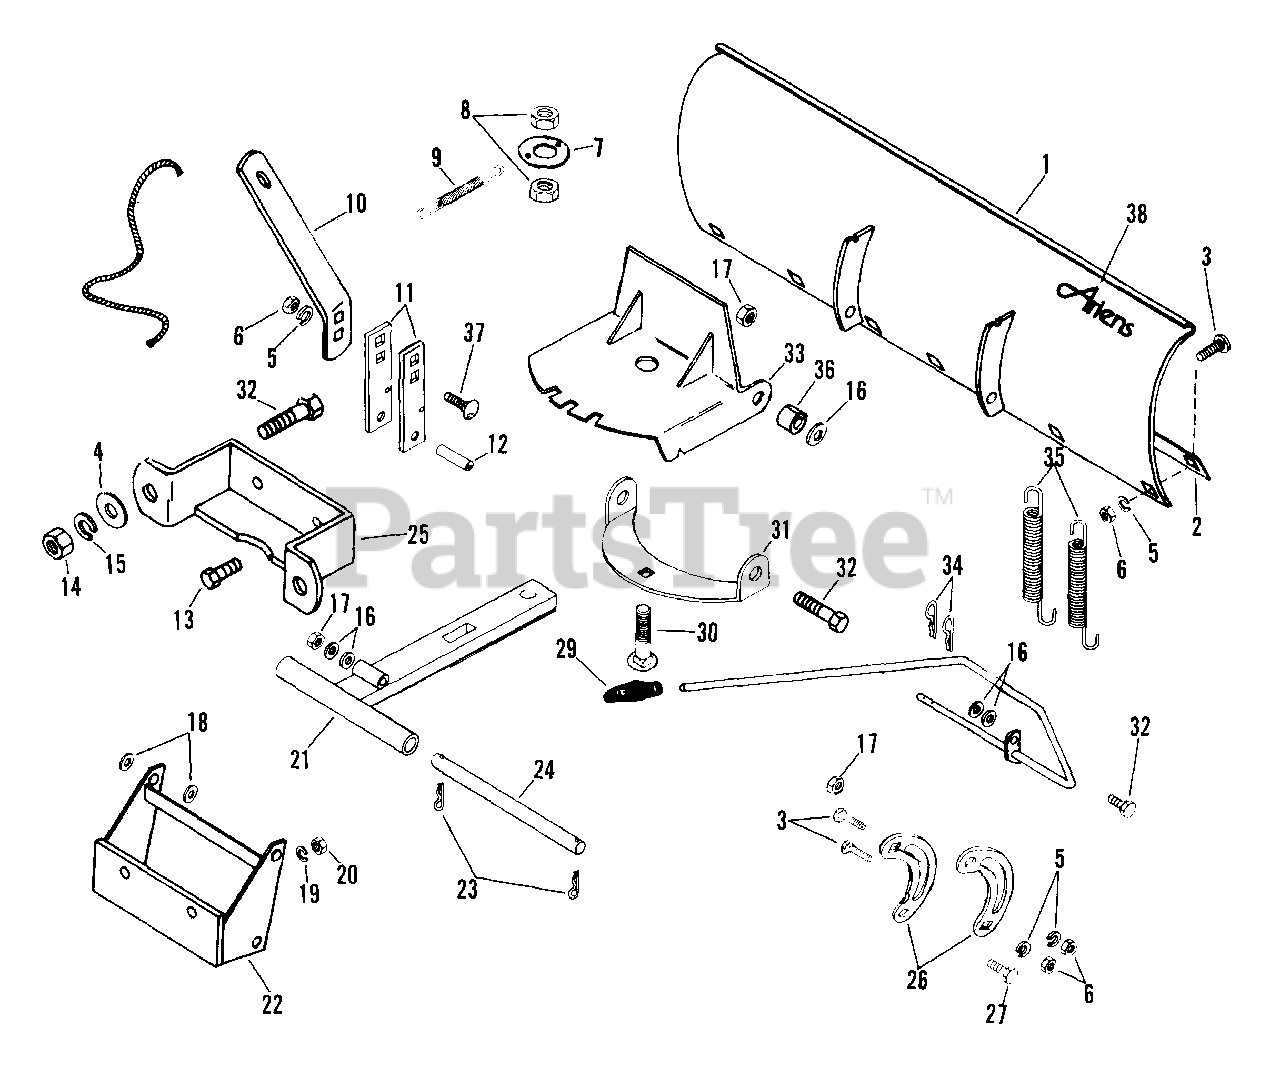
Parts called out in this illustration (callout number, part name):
1	40 INCH SNOW BLADE
2	WEAR BAR
3	BLT-RDHDSQSHNK .38-16X1.00 PL
5	WSHR-LK .375X.115 HVY PL
6	NUT-HEX .375-16
7	LATCH SPRING WASHER
8	NUT-JAM .75-10 PL
9	SG-TENS .106X.56X2.75 WLD 10
10	PIVOT BLOCK EXTENSION
11	BAR PIVOT LOCK
12	PIN-ROLL .250X1.00
13	BLT-HEX .25-20X1.00 PL GR5
14	NUT .50-13 PL
15	WSHR-LK .500X.151 HVY PL
16	WSHR-FL-STL .531X1.062X.095 PL
17	NUT-LK-CTR .50-13
18	WSHR-FL-STL.656X1.312X.095 PL
19	WSHR-LK .250X.077 HVY PL
20	NUT-HEX .250-20 PL
21	PUSH TUBE ASSEMBLY
22	MOUNT BRACKET
23	@PIN-CTR .16X1.25 EXTPRSQCT YZ
24	PIVOT ROD
25	TRACTOR MOUNT
26	LIFT LINK
27	BLT-HEX .50-13X3.00 PL GR2
28	LIFT HANDLE
30	BLT-RDHDSQNK .75-10X3.0
31	LOWER PIVOT PLATE
32	BLT-HEX .50-13X1.50 PL GR2
33	UPPER PIVOT PLATE
34	PIN-HAIR INT .09X.188 PL
35	SG-TENS .125X.81X6.50 WLD 10
36	PIVOT BUSHING
37	BLT-RDHDSQNK .38-16X1.25 PL
38	DECAL - ARIENS
